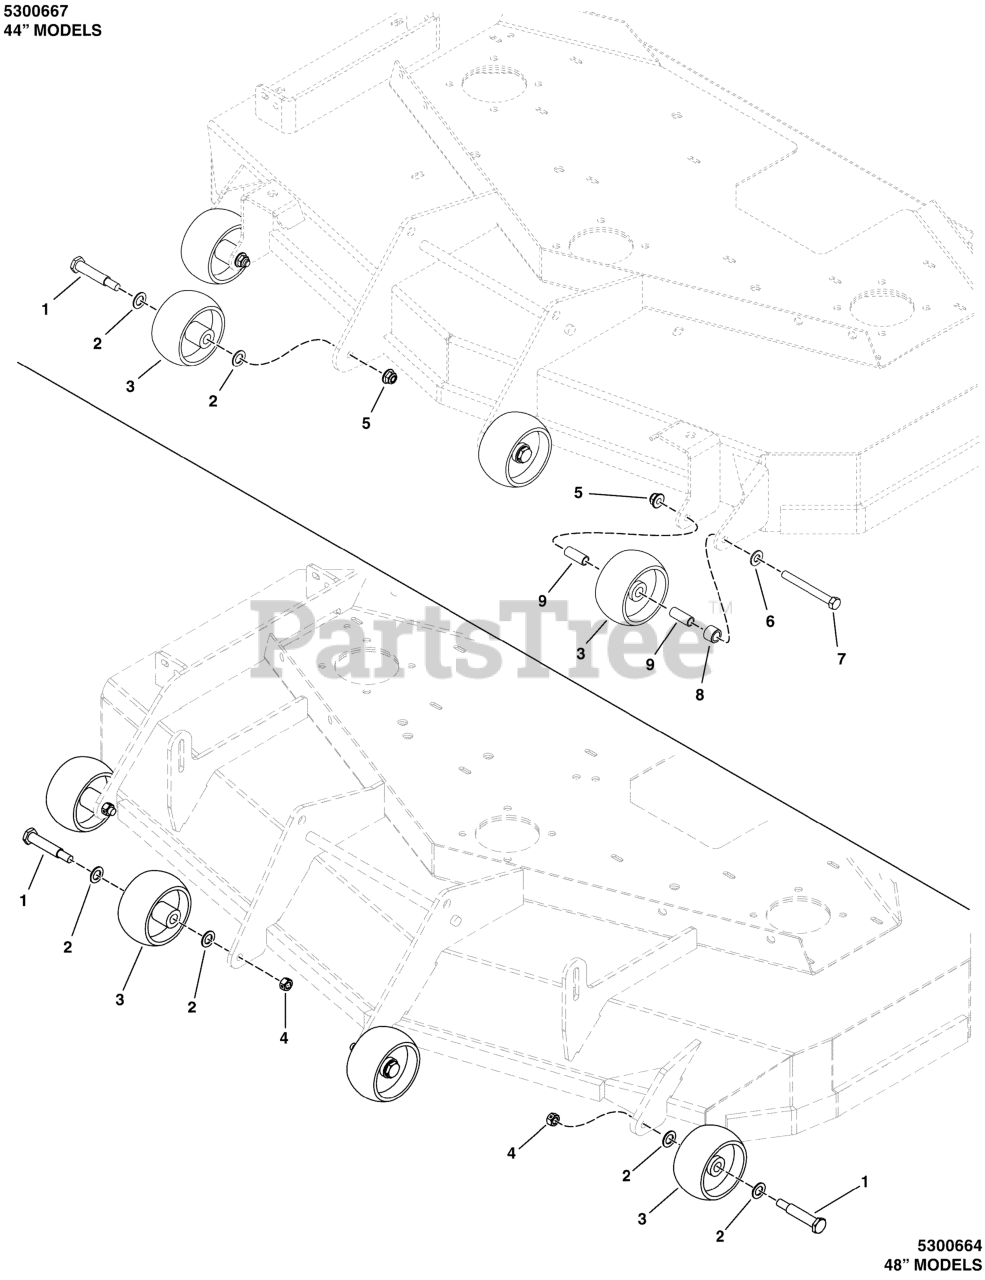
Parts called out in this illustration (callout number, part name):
1	BOLT-WHEEL 3/8-16X2.781 .750 THRD
2	WASHER,.516IDX.875ODX.06,FLAT,ZC/CL
3	WHEEL- 2.00 WIDE 3.88 DIA 0.531ID POLY
4	NUT, 3/8-16 HEX SIDE LOCK
5	NUT, 3/8-16 HEX NYLOCK FLANGE
6	WASHER, 3/8 SAE
7	BOLT, 3/8-16 X 3-1/2" GD5 CZ
8	SPACER, .51 X .75 X .56
9	SPACER, .38 X .50 X 1.25, CZ
